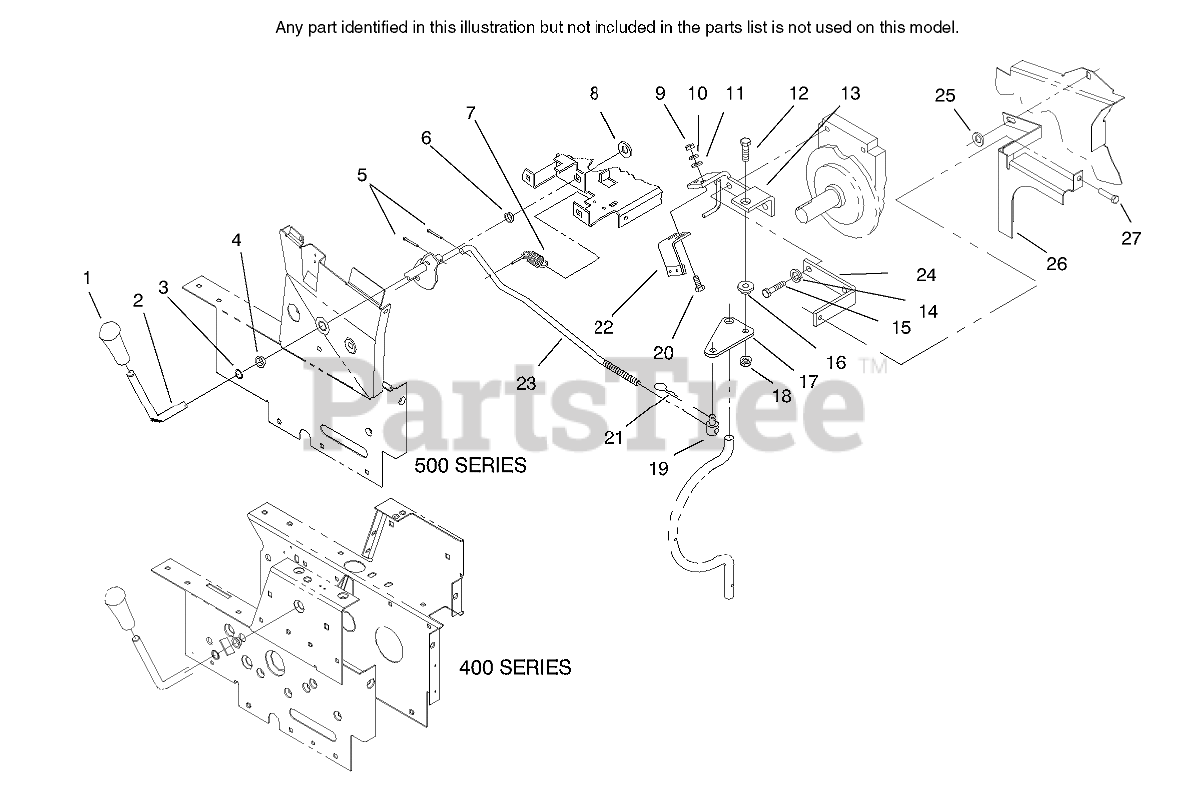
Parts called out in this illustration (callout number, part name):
2	PTO CLUTCH LEVER ASM
3	RING-EXT GRIP
4	BUSHING-NYLINER
5	PIN-COTTER
6	NYLINER BUSHING
7	SPRING
8	SHIM-WASHER
9	NUT-JAM
10	WASHER-LOCK
11	WASHER-FLAT
13	Bracket-PTO
14	WASHER-LOCK
15	SCREW-HH
16	SPACER-LIFT LINK
17	PLATE
18	NUT-LOCK, NI
19	TRUNNION
20	SCREW-CARR
21	PIN-HAIR
22	BRAKE ASM
23	ROD-PTO CLUTCH
24	Bar-Support
25	WASHER-PLAIN
27	Bolt
